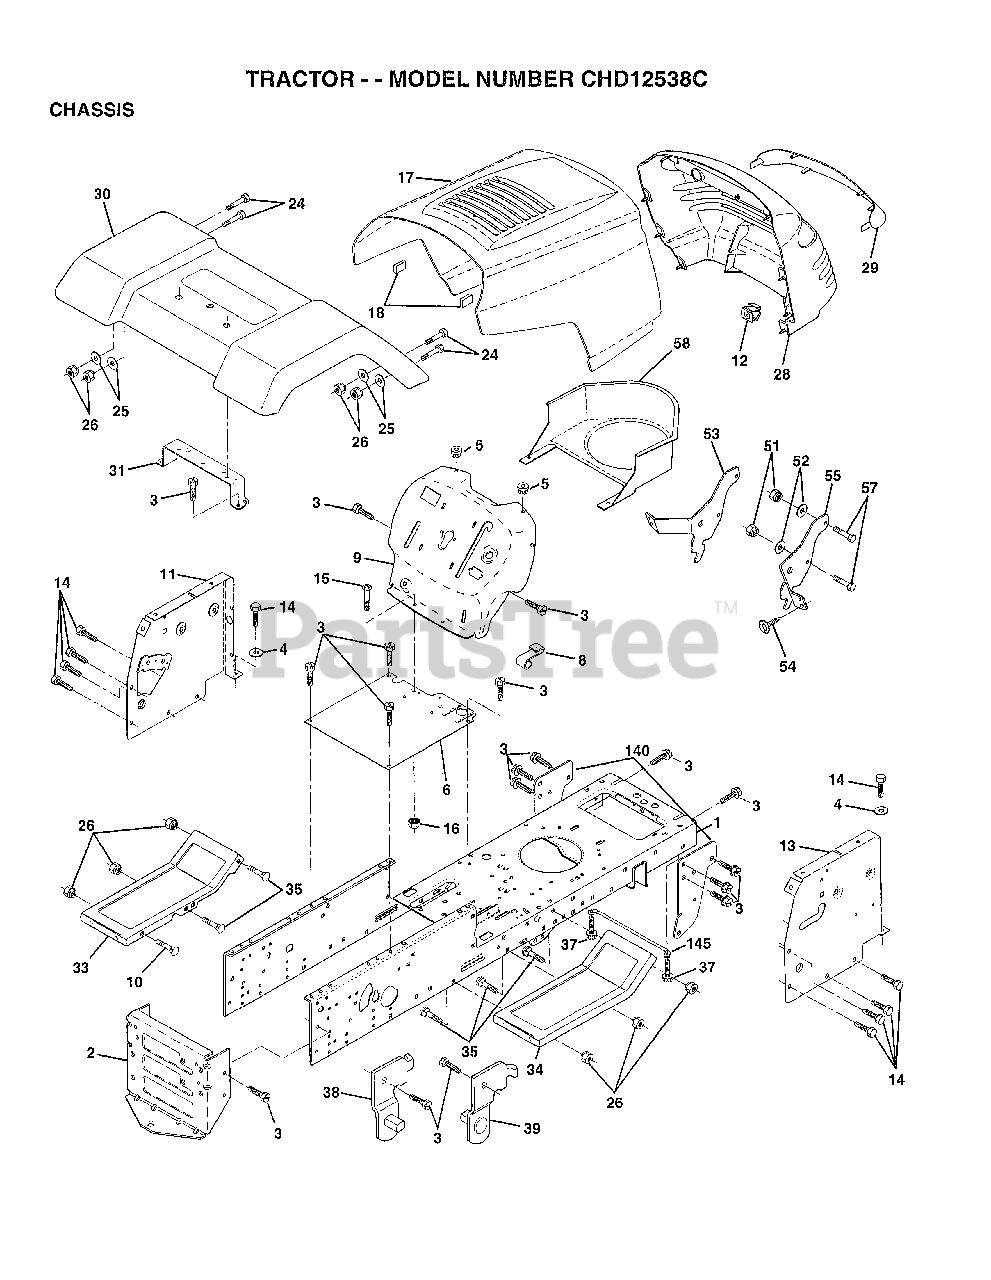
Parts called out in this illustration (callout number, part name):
3	SCREW
4	WASHER
5	BUMPER-HOOD/DASH
6	"SADDLE-SLKSCR,5SP"
8	CLIP.RETAINER
9	DASH SILKSCREEN
11	"PANEL-DASH,LH"
12	CLIP.TINNERMAN
14	SCREW LT
15	SCREW
17	HOOD.STEEL.ASSY
24	BOLT
25	WASHER
26	NUT
28	GRILLE
29	LENS QUADRA
30	FENDER PNT LT
31	BRKT FENDER
33	FOOTREST.LH.PERF.
34	FOOTREST.RH.PERF.
35	BOLT
38	BRACKET ASM LH
39	BRACKET ASM RH
51	NUT
52	WASHER
53	BRACKET.GRILLE.LH
54	SCREW.HEX.WS.HD
55	BRACKET.GRILLE.RH
58	AIR DUCT
140	BRKT SUSPENSION
145	"ROD POVOT,CHASSIS"
